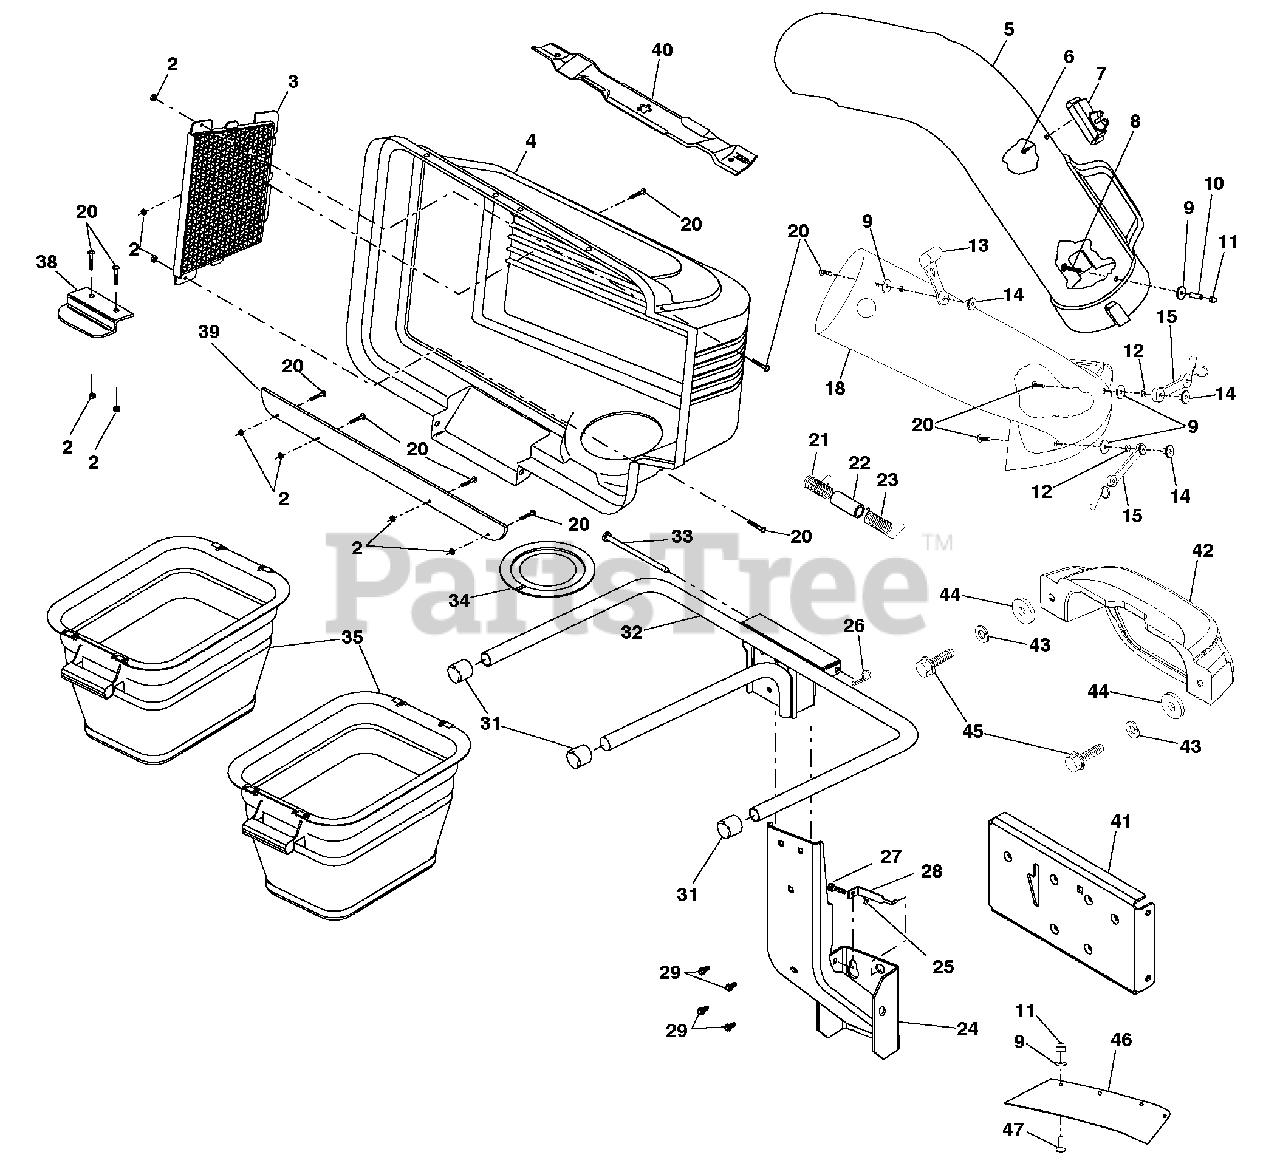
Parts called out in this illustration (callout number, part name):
2	Nut, Crown Lock #10-24
3	Screen, Cover
4	Cover Assembly
5	Chute, Upper
6	Screw, Special #10-14 X 1/2
7	Full Bag Indicator
8	Screw, #10-24 X 1-1/8
9	Washer 3/16 X 3/4 X 16 Ga.
10	Spacer, Split
11	Nut, Acorn #10-24
12	Washer, Lock
13	Latch, Chute
14	Nut, Weld
15	Latch, Hook
18	Chute, Lower
20	Screw #10-24 X 5/8
21	Spring, Cover L.H. (Black)
22	Spacer, Cover
23	Spring, Cover R.H. (Gray)
24	Support Assemble
25	Locknut
26	Spring, Retainer
28	Bracket, Lock
29	Bolt, Shoulder 5/16-18
31	Plug, Tubing End
32	Bagger, Frame
33	Pin, Hinge
34	Gasket, Cover
38	Latch Handle, Cover
39	Strip, Reinforcement
41	Drawbar
42	Counterweight
43	Washer
44	Lock Washer
46	Deflector Guard
47	Screw, #10-24 X 1/2
